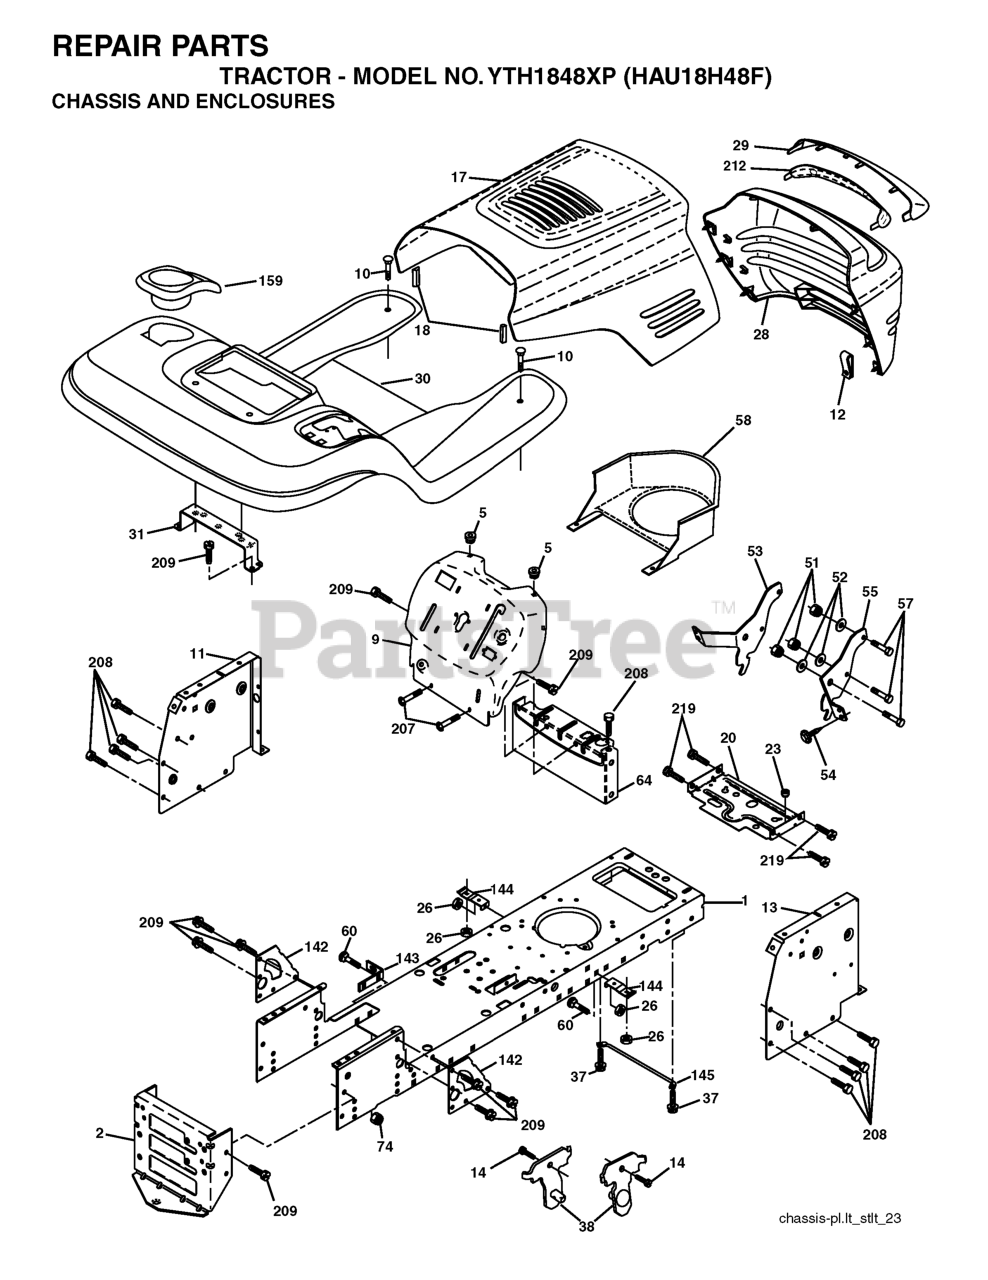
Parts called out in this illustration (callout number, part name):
1	CHASSIS STAMPING
2	DRAWBAR, 12GA
5	BUMPER.RUBBER.HOOD
9	DASH SLKSCR
10	BOLT D
11	PANEL.DASH.LH.LTX
13	PANEL ASM, DASH RH
14	SCREW LT
17	HOOD ASM.
18	BUMPER.HOOD.LARGE.1.75"
20	PLATE MTG.BATTERY/FUEL TANK
23	BUSHING.SNAP.NYL.BLK.
26	NUT
28	GRILLE/LENS ASM
29	LENS
30	FENDING
31	BRACKET.SUPPORT.FENDER
37	Screw 5/16-18 x 1/2 Hex, Self Tapping 5/16-18 x 1/2
38	BRACKET.ASM.PIVOT.MOWER.REAR
51	LOCKNUT.NYLOC.1/4-20
52	WASHER
53	BRACKET.GRILLE.LH
54	SCREW.HEX.WS.HD.8-18 X 7/8
57	BOLT
58	DUCT, INTAKE AIR
60	Bolt - Rd. Hd. Sq. Neckiage 3/8 16 x 3/4
64	DASH LOWER
142	PLATE REINFORCEMENT
143	BRACKET, SWAYBAR CHASSIS
144	BRKT, FOOT REST
145	ROD PIVOT CHASSIS/HOOD
159	CUPHOLDER
207	SCREW, 5/16-18 X 1/2
208	SCREW 3/8-16X1/2
209	SCREW, 3/8-16X3/4
212	REPL BY 532 1745-03
219	SCREW
